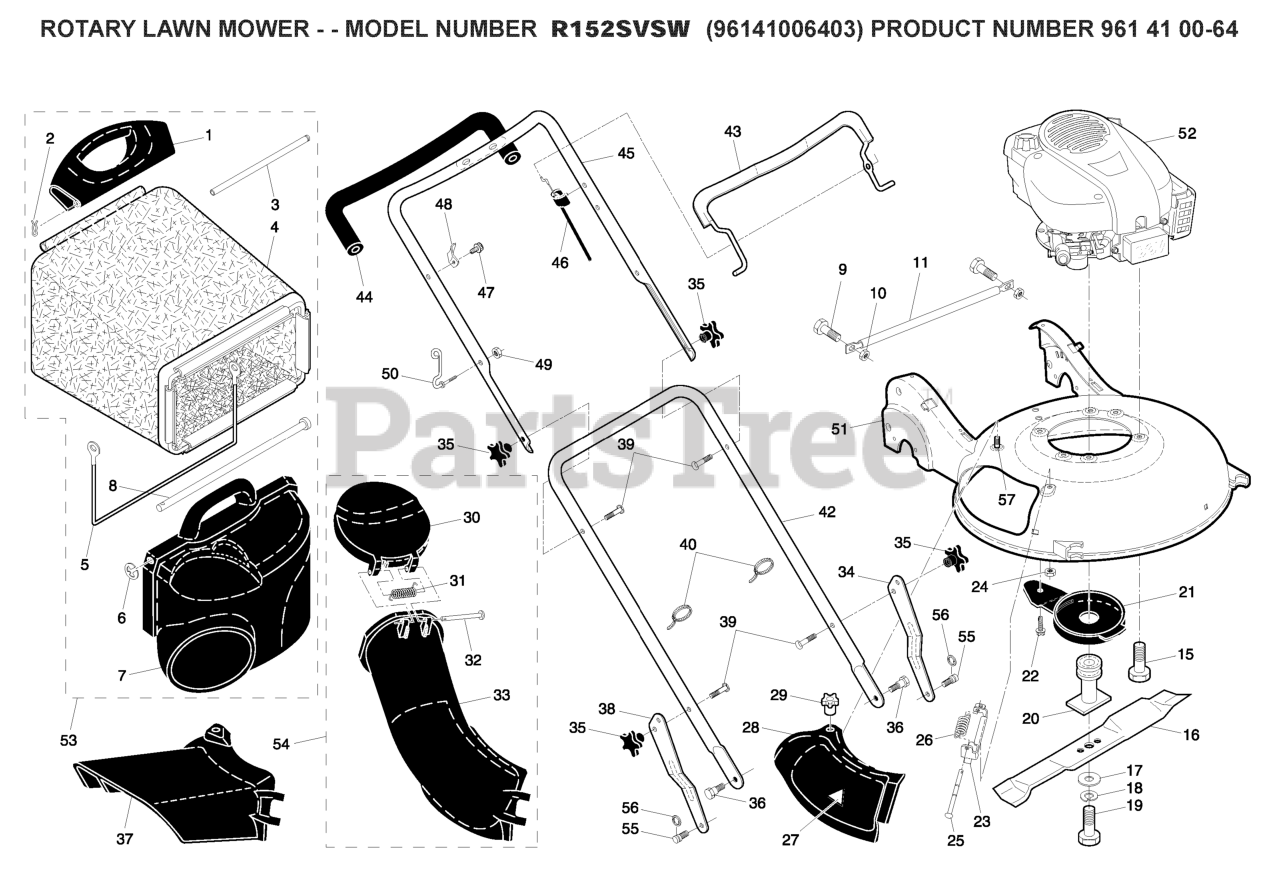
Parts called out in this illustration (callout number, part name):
1	HANDLE.GRASSBAG.REAR.H-GRAY
2	COTTER PIN (3 2)(2 2MC)
3	ROD.REAR.HANDLE.YELLOW
5	FRAME, GRASSBAG
7	DOOR, GRASSBAG
8	ROD, PIVOT
10	LOCKNUT.NYLOC.1/4-20
11	TUBE, REAR SKIRT
15	BOLT 3/8-16X1-1/8
16	Blade, 21"
17	WASHER,HARDEN
18	LOCKWASHER
19	BOLT.HD.HEAD.3/8-24X2.50 (2 2)
20	ADAPTER.BLADE
21	DEBRIS SHEILD
22	SCREW 1/4X20
23	BRACKET.ASM.HINGE
24	NUT.HEX.FLANGE.1/4
25	ROD.HINGE.1/4"3.82"
26	SPRING.MULCH.DOOR
27	DECAL.INTERNATIONL.CUTFINGER
28	MULCHER DOOR
29	KNOB.MULCH.DOOR
30	CHUTE.DOOR.21.HV.H-GRAY
32	ROD.HINGE.1/4"3.82"
33	DISCHARGE CHUTE PLASTIC
34	ADJUSTMENT BRACKET, LOWER LH
35	KNOB.HANDLE.STAR.HUSQ.GRAY
36	SCREW.5/16X.680.TRIM.H
37	GUARD.CLIP.ON.21.HV.GRAY
38	BRACKET.ADJ.LOWER.HDL.RT.GREY
39	BOLT, HANDLE 5/16-18X1.75
40	TIE GUIDE
42	HANDLE.LOWER.GREY
43	BAIL CONTROL
44	GRIP.HANDLE.FOAM.WIDE.(1 SIDE)
45	HANDLE.ASM.UPPER.W/GRIP
46	CABLE.MZR.SNAP-IN
48	BRACKET
49	NUT
50	GUIDE.ROPE.WALK.MOWER
53	Grassbag Assembly, Complete
54	CHUTE.LOWER.ASM.WALK.MOWER
56	E-RING 7/16 RE
57	STUD.SHOULDER.T45.BZP
